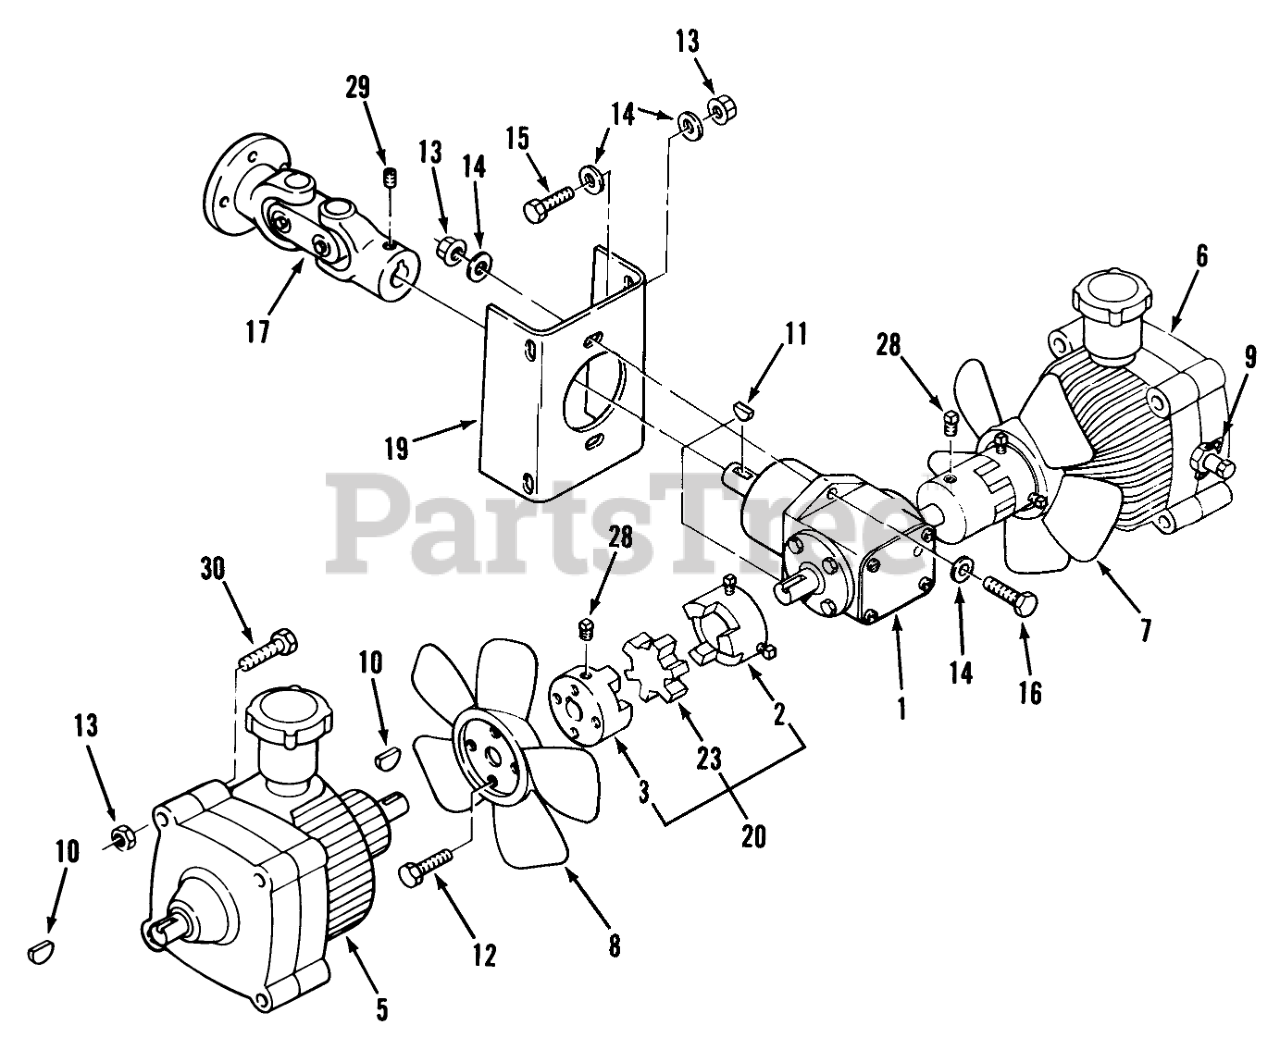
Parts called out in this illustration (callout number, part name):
1	GEAR BOX-T
2	COUPLING-KEYED
3	COUPLING-KEYED
5	TRANS-HYDRO CCW.
6	TRANS-HYDRO CW
7	Fan-LH, Clockwise
8	BLADE-FAN R.H.
9	CLIP-DUMP VALVE
10	KEY-HIPRO
11	KEY-HI-PRO
12	Screw
13	NUT
14	Washer
15	BOLT
16	Bolt
17	U-JOINT ASSY W/FLANGE
19	BRACKET-GEAR BOX B
20	Coupler Complete (Includes 2, 3 & 23)
23	SPIDER-COUPLING
28	Screw-Sq. Hd. Set
29	Setscrew 3/8-16 x 1/2
30	Screw-Hex. Hd.
